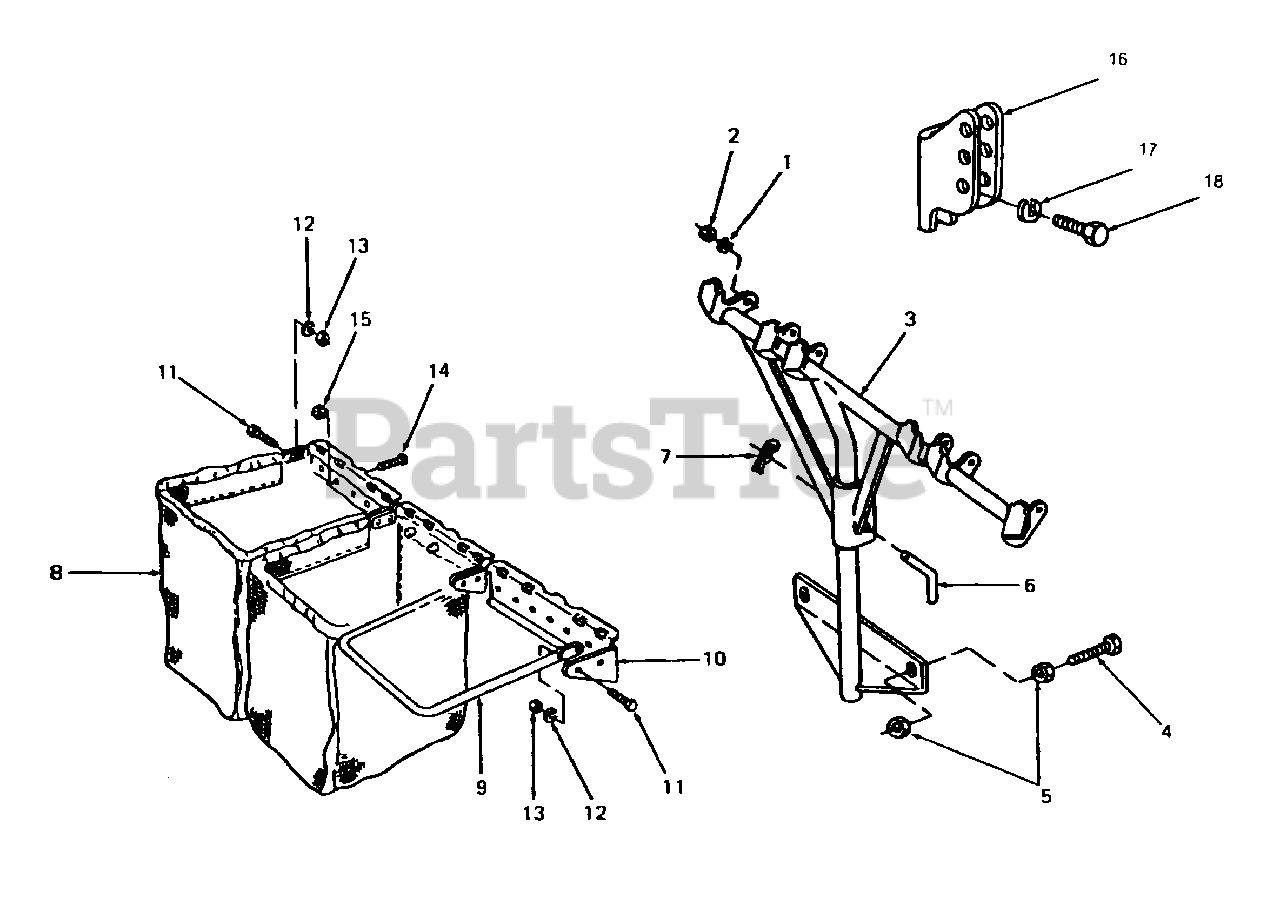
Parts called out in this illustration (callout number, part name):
1	Washer, Lock, 3/8
2	Nut, Hex, 3/8-16
3	Tube Assy, Catcher Support
4	Screw, Hex Cap, 3/8-16 X 1.25 Lg.
5	Nut, Hex Jam, 3/8-16 GR5
6	Pin, Right Angle Clevis
7	Pin, Internal Cotter, 5/8 Dia.
8	Bag, Grass Catcher
9	Frame, Catcher Bag
10	Bracket, Bag Frame Hanger
11	Screw, Hex Cap, 1/4-28 X .75 Lg.
12	Washer, Lock, 1/4
13	Nut, Hex, 1/4-28
14	Screw, Truss Mach, #10-24 X .38 Lg.
15	Nut, Hex Sems, #10-24
16	Hitch Bracket
17	Washer, Lock, 3/8
18	Screw, Hex Cap, 3/8-16 X .88 Lg.
